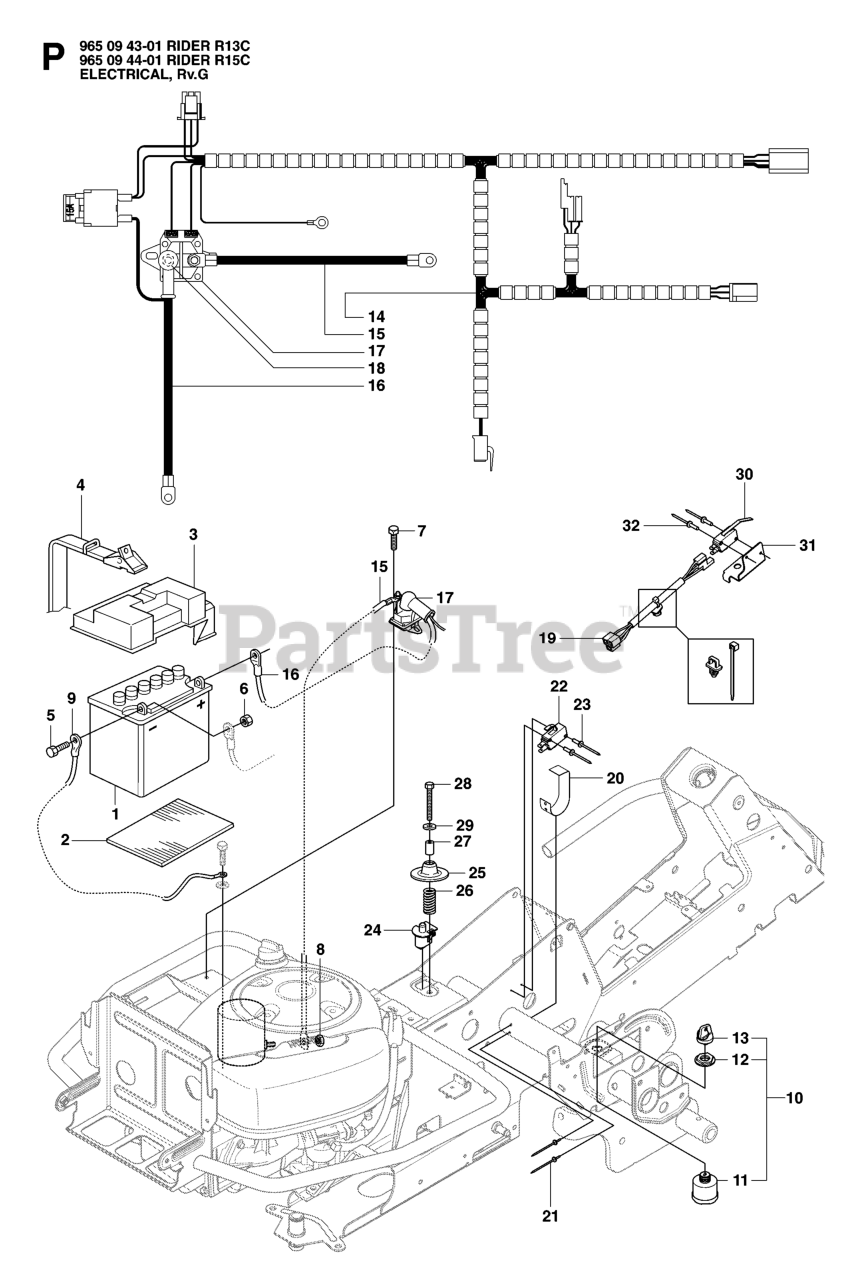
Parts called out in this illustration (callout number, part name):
1	BATTERY - DRY
10	IGNITION SWITCH
11	IGNITION SWITCH
13	IGNITION KEY
19	WIRING
22	%BRAKER
27	SPACER TUBE
28	SCREW
29	WASHER BRB 8.4X17
30	RP MICRO SWITCH
